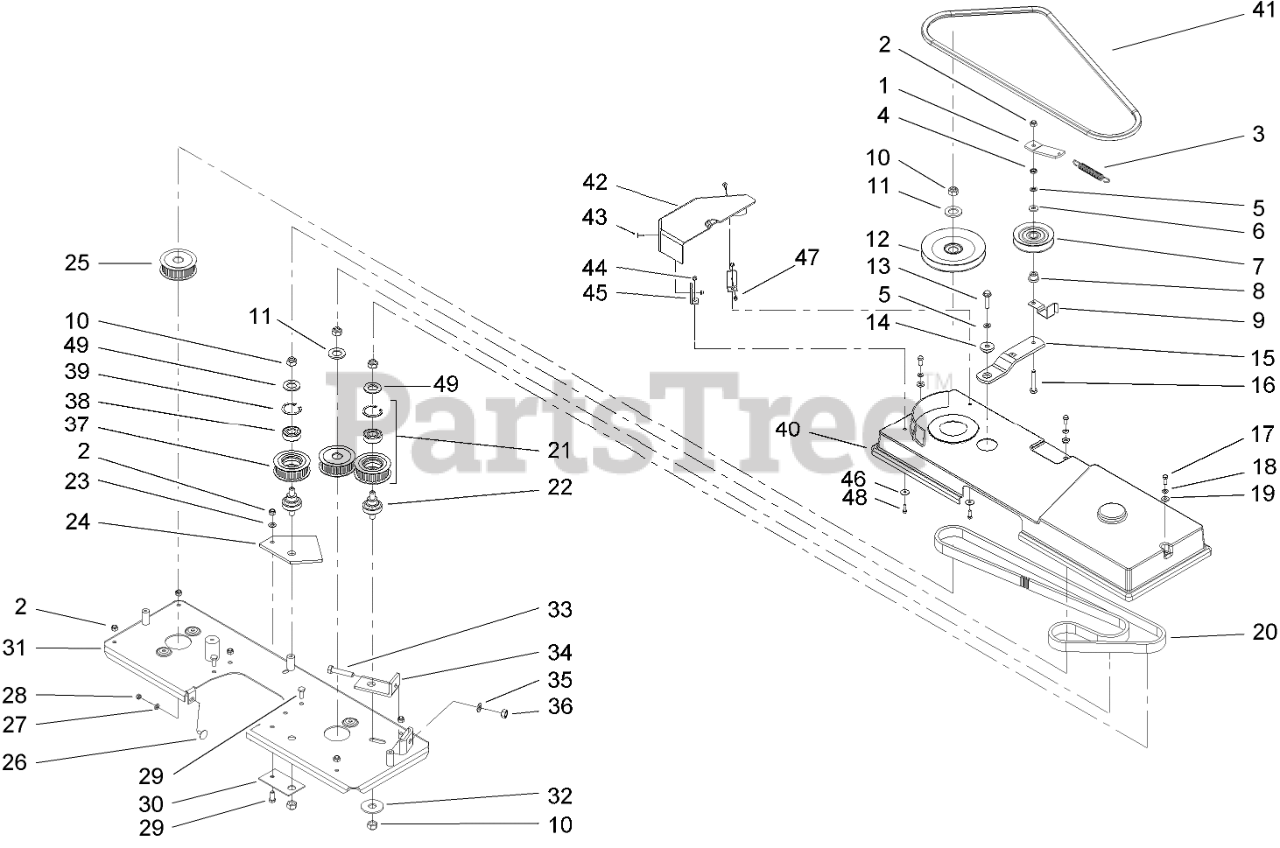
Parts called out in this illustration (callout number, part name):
1	LEVER-ENGAGEMENT
2	NUT
3	SPRING
4	NUT-JAM
5	WASHER-LOCK, SPRING
6	Washer-Flat
7	PULLEY-IDLER
8	BUSHING
9	RETAINER-BELT
10	NUT-LOCK, HEX NI
11	WASHER-FLAT
12	PULLEY-DRIVE
13	SCREW-HHF
14	SHIM-ARM, IDLER
15	ARM-IDLER
16	Screw-HH
17	SCREW-HH
18	Washer-Flat
19	WASHER-RUBBER
20	Belt-Cog
21	COG PULLEY ASM
22	PIN-PULLEY, Cog
23	WASHER-PLAIN
24	SUPPORT-PULLEY
25	PULLEY-COG, DRIVE
26	SCREW-CARR
27	WASHER-FLAT
28	NUT-LOCK
29	SCREW-HH
30	PLATE-ANCHOR
31	PLATE-DRIVE, BLADE
32	WASHER
33	SCREW-HH
34	BRACKET-IDLER
35	WASHER-FLAT
36	NUT
37	Pulley-Cog
38	BEARING-BALL
39	RING-LOCKING
40	Belt-Cover
41	V-BELT
42	GUARD-BELT
43	SCREW-HH
44	NUT-LOCK
45	BRACKET
46	WASHER-FLAT
47	NUT-LOCK
49	WASHER-FLAT
